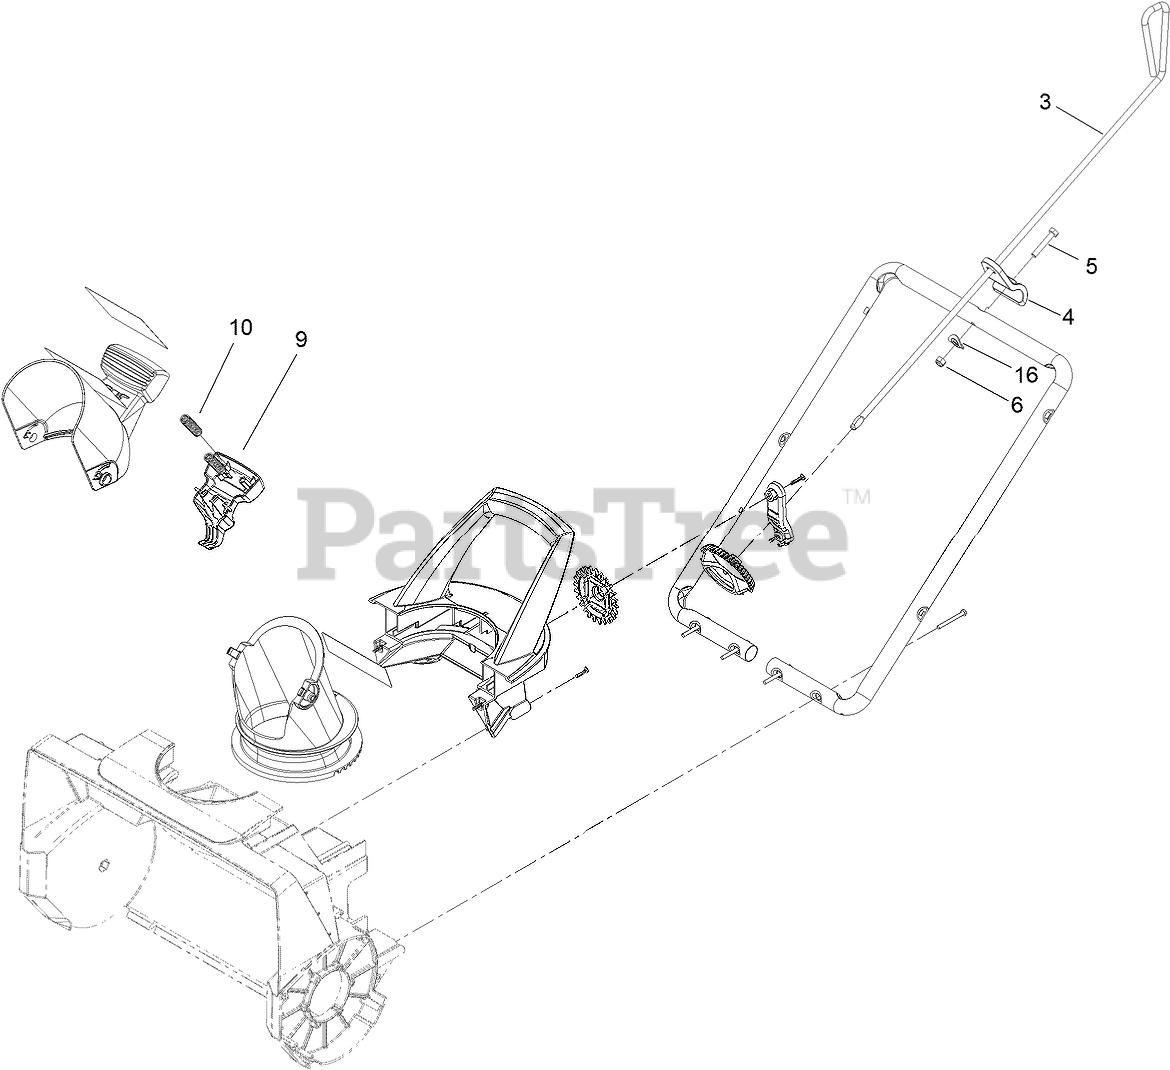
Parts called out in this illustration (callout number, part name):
3	ROD-CONTROL, CHUTE
4	GUIDE-ROD, CHUTE
5	NUT-HEX
6	SCREW-HH TAP
9	TRIGGER-DEFLECTOR
10	SPRING-COMPRESSION
16	WASHER-CUP
